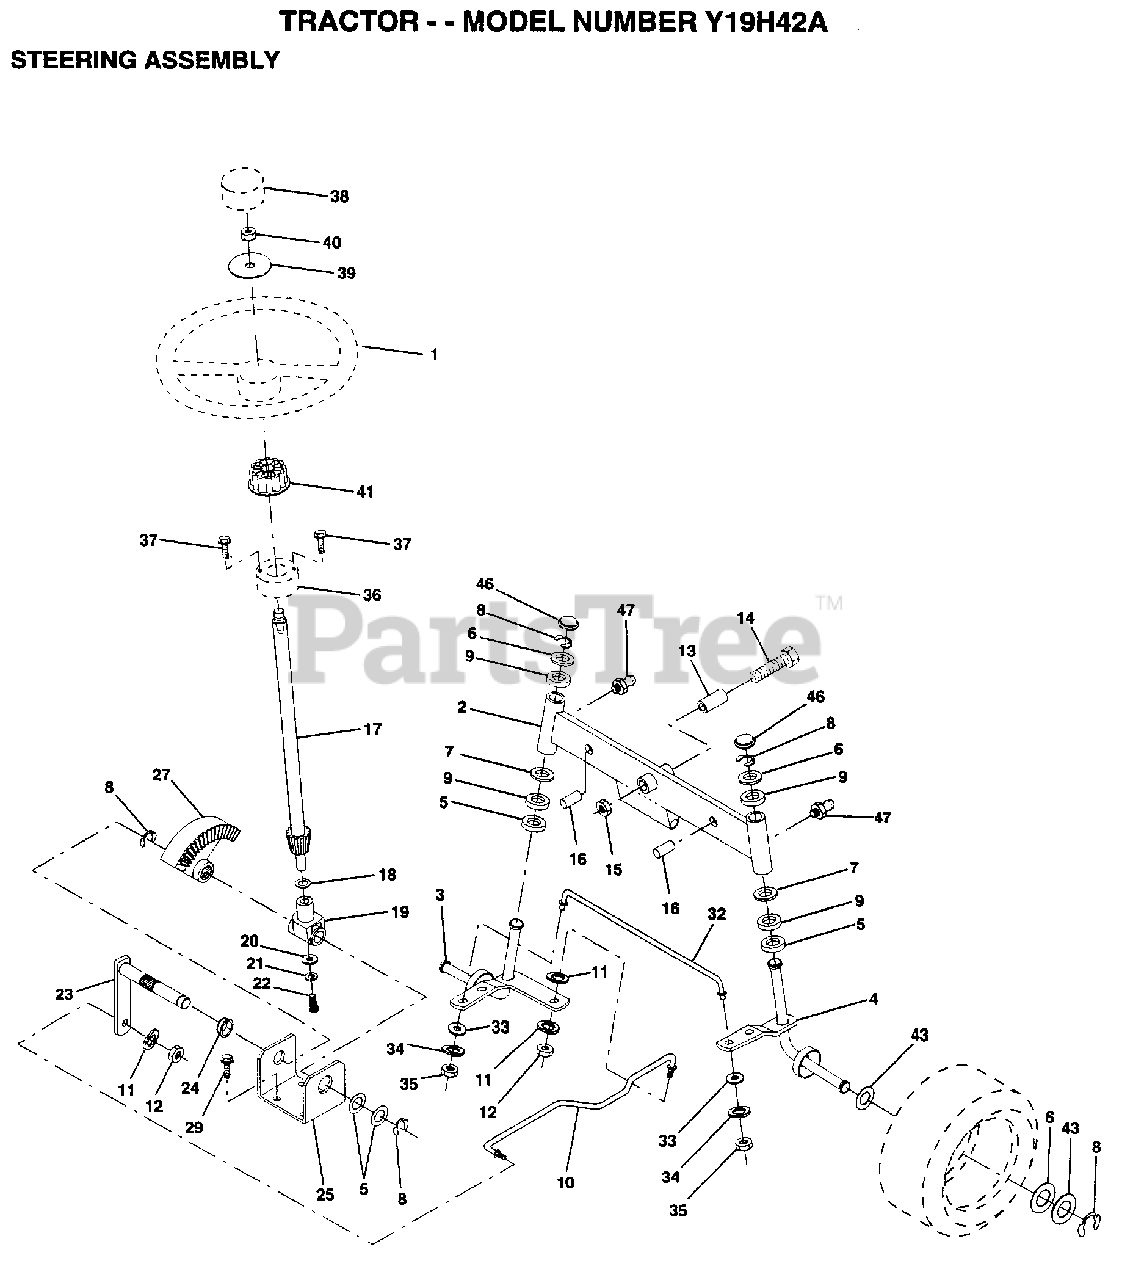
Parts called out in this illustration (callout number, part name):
1	Wheel Steering
2	AXLE ASM FRONT
3	SPINDLE RH
4	SPINDLE RH
5	WASHER .T
6	WASHER
7	WASHER
8	RING
9	COL. SRTG. BEAR.
11	WASHER, LOCK 3/8
14	BOLT HEX 5/8-11
15	"NUT-LOC,FLANGE LT"
16	AXLE PIN
18	THRUST WASHER
20	Washer Shim 1/4 x 5/8 x .062
21	LOCKWASHER
22	"SCREW,SPECIAL"
24	NYLINER T (7283A)
25	BRKT,STEERING
27	GEAR SECTOR
29	SCREW
32	TIE ROD
33	WASHER M
34	LOCKWASHER
35	NUT.LOCK.5/16-24
36	BUSHING.STRG.3/4
37	SCREW.10-24X1/2
38	INSERT STEERING
43	WASHER (2513009)
46	CAP
47	ZERK M
